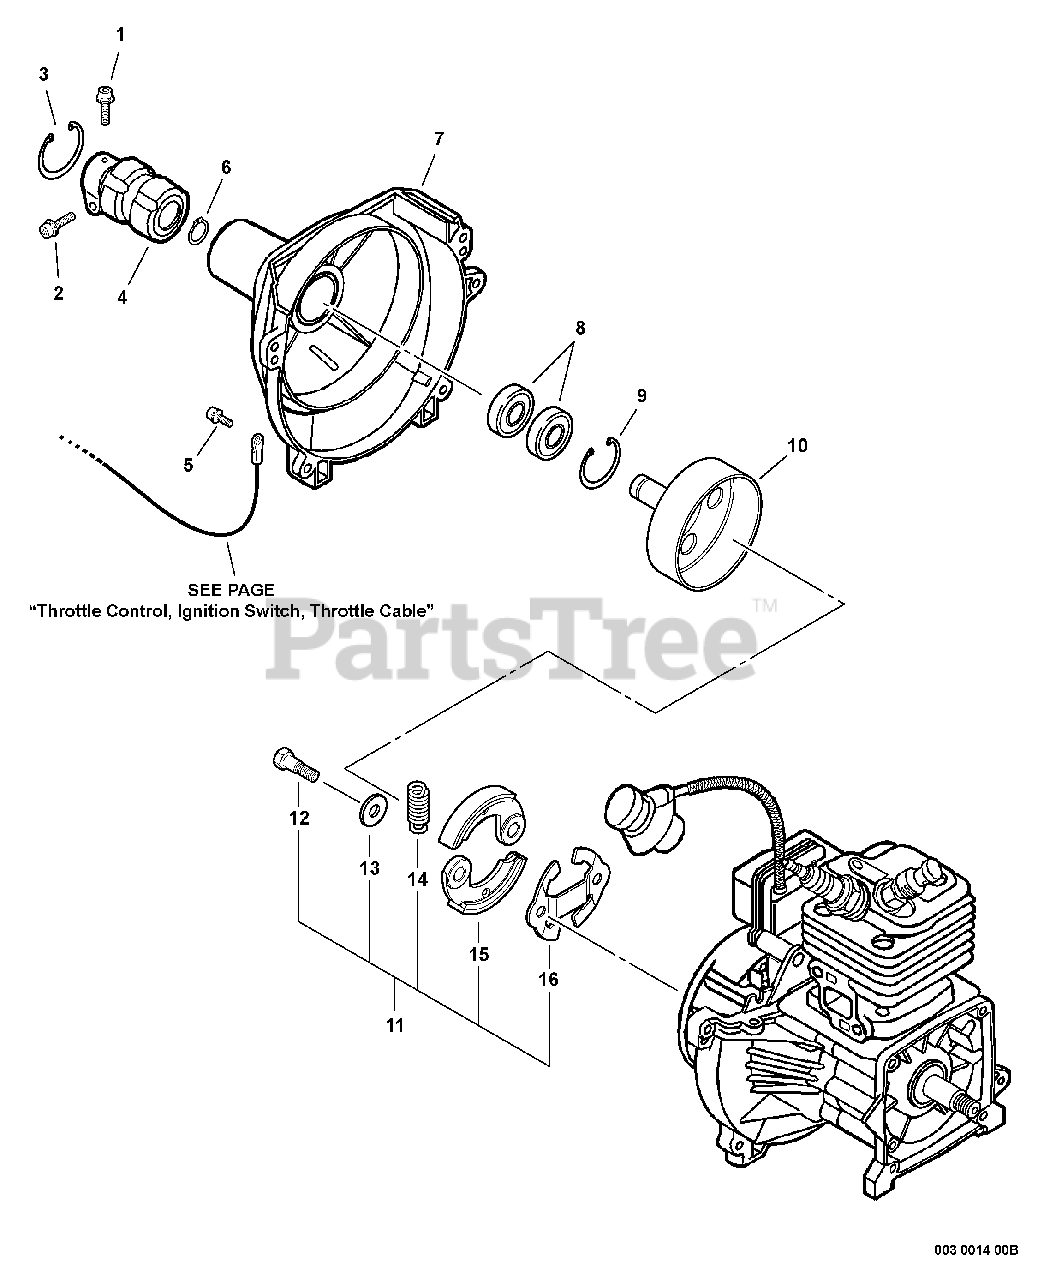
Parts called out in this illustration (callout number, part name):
1	SCREW - 5X12
2	SCREW - 5X28
3	RING, RETAINING - 45
4	CUSHION
5	SCREW - 5X20
6	RING, RETAINING - 12
7	CASE, FAN - ORANGE
8	BEARING, BALL - 6001
9	RING, RETAINING - 28
10	DRUM, CLUTCH
11	CLUTCH ASSY
12	BOLT, CLUTCH
15	SHOE, CLUTCH
16	PLATE, SPRING
